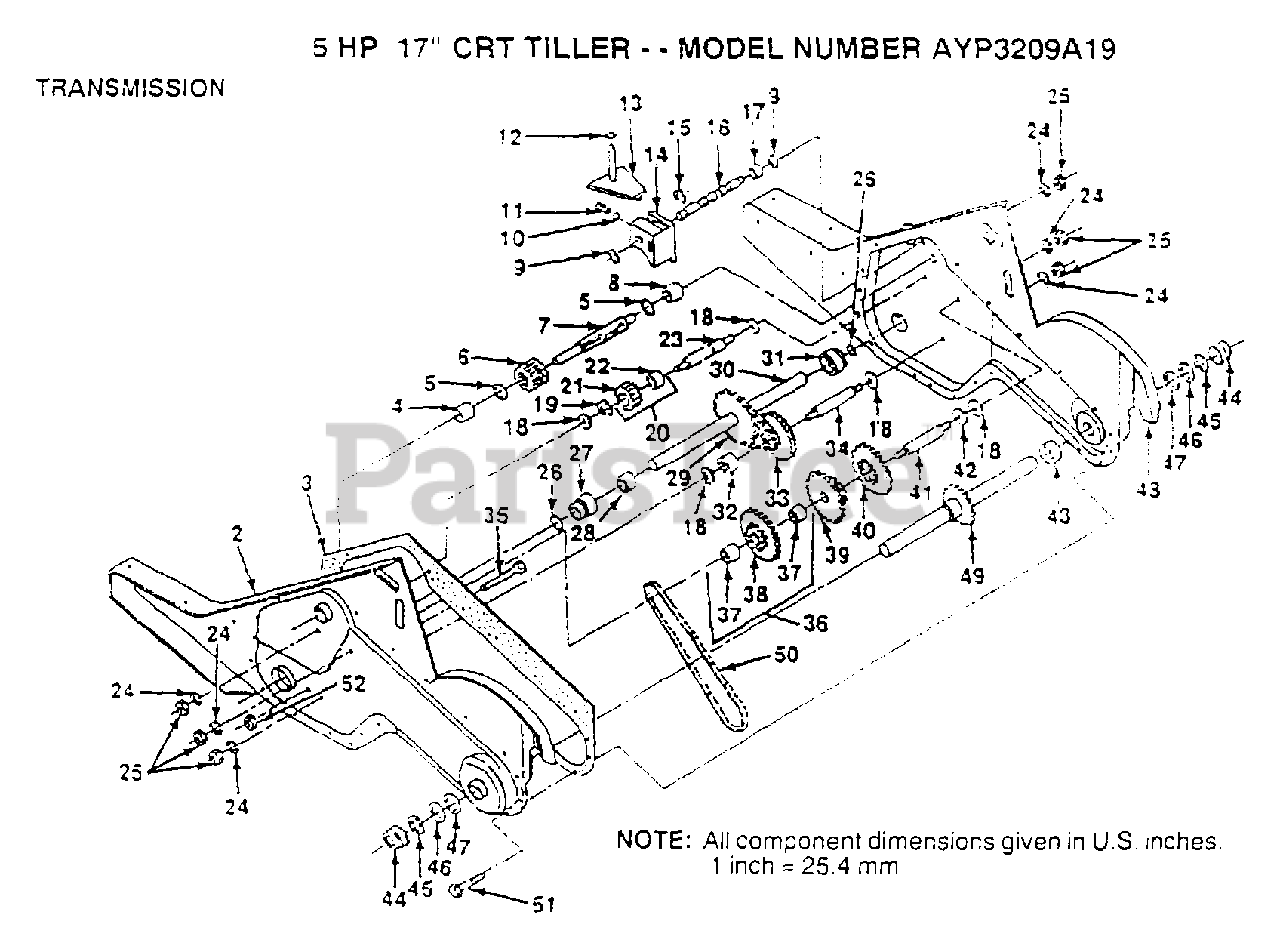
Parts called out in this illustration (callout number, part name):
3	GASKET TI
4	NEEDLE BRNG LT
5	"T, BEARING"
6	PINION-INPUT CRT
7	SHAFT-INPUT CRT
8	"TI, BEARING"
9	WASHER SEAL CRT
11	SPRING-SHIFT CRT
12	O-RING TI
13	ARM ASSY CRT
14	SHIFT FORK TI
15	KLIP RING
16	SHAFT SHIFT CRT
17	SPACER SPLIT CRT
18	WASHER
19	KLIP RING
20	GEAR ASSY CRT
21	GEAR-REV IDLR CRT
22	NEEDLE BEARING TI
23	SHAFT CRT
24	LOCKWASHER
25	NUT.ASF.HEX.7/16
26	O RING CRT
27	"CRT, BEARING"
28	BUSHING TI
29	CHAIN CRT
32	SPACER TI
33	SPRCKT 8 GEAR CRT
34	SHFT 2ND RED. CRT
35	SCRW WHIZ LOK CRT
37	BEARING
39	GEAR TI
40	GEAR TI
41	REDUCTION SHFT TI
42	BRNG RACE
43	SPACER TI
44	CUP.FORMED.
45	RING SPIRAL CRT
49	SHAFT ASSY TI
51	SCREW CRT
52	NUT.HEX.5/16-18
